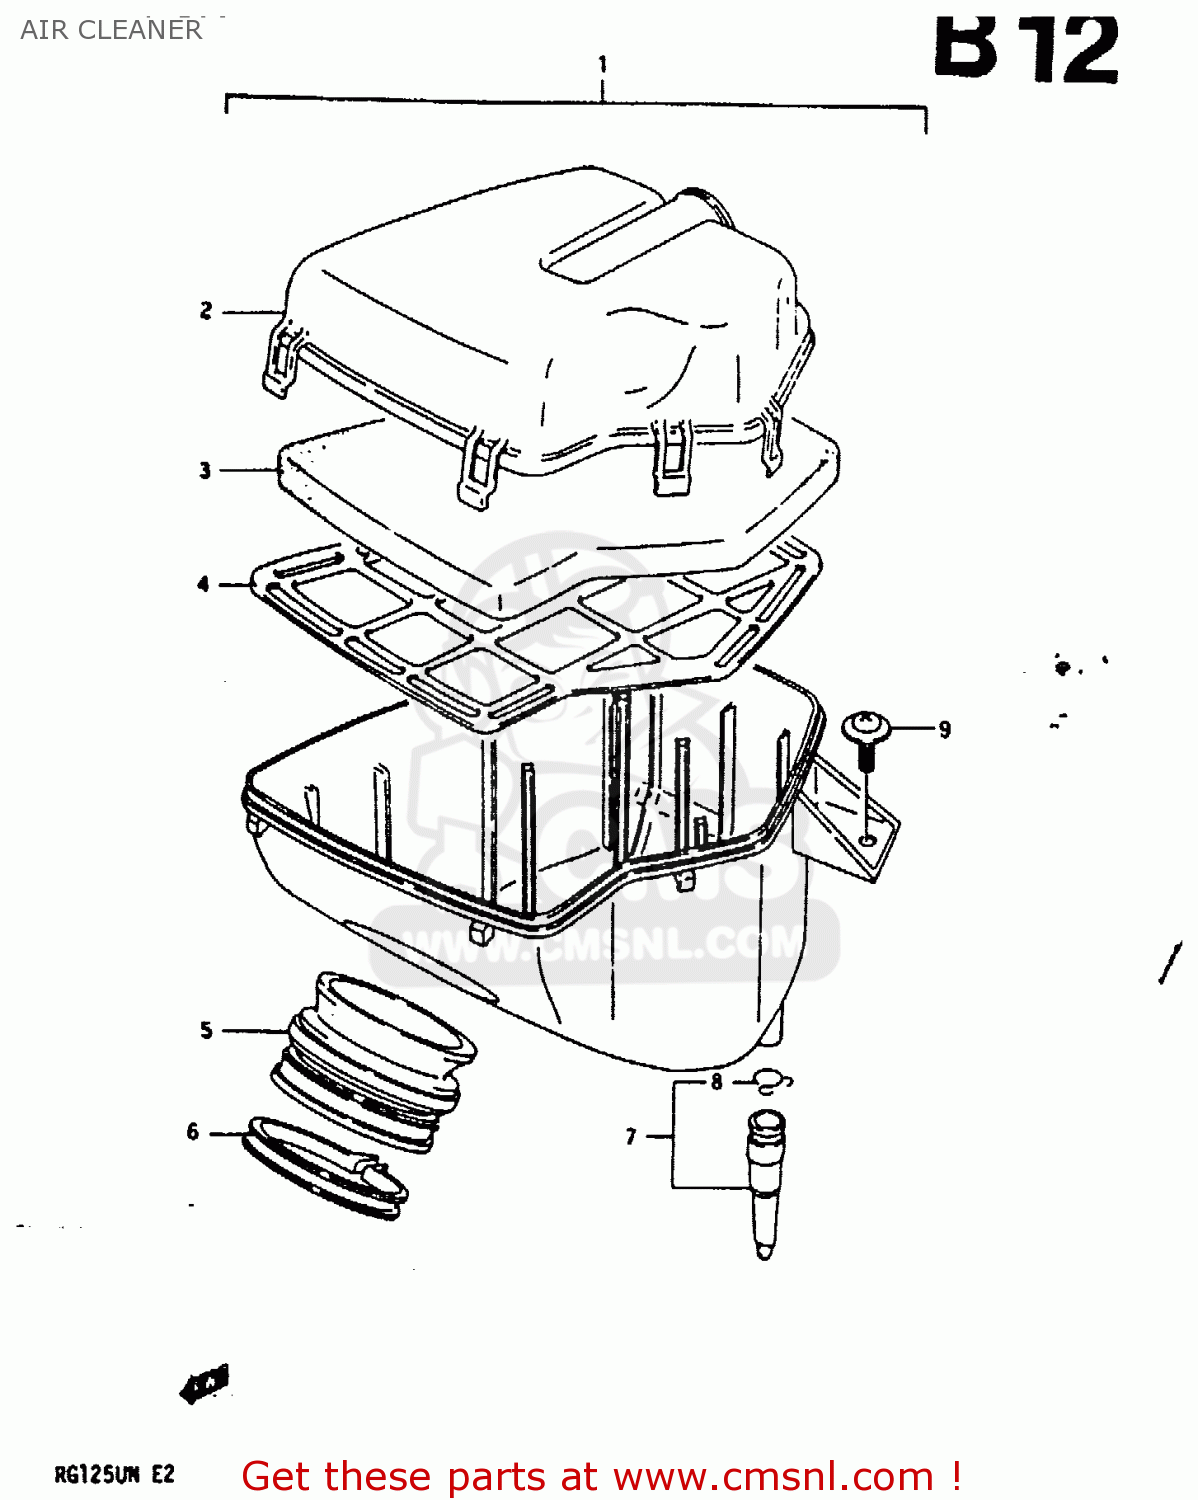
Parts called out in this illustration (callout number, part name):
1	CLEANER ASSY, AIR
2	CAP,AIR CLEANER
3	FILTER,AIR
4	HOLDER,FILTER
5	TUBE,OUTLET
6	CLAMP
7	CAP,DRAIN
8	CLIP
9	SCREW(6X16)
